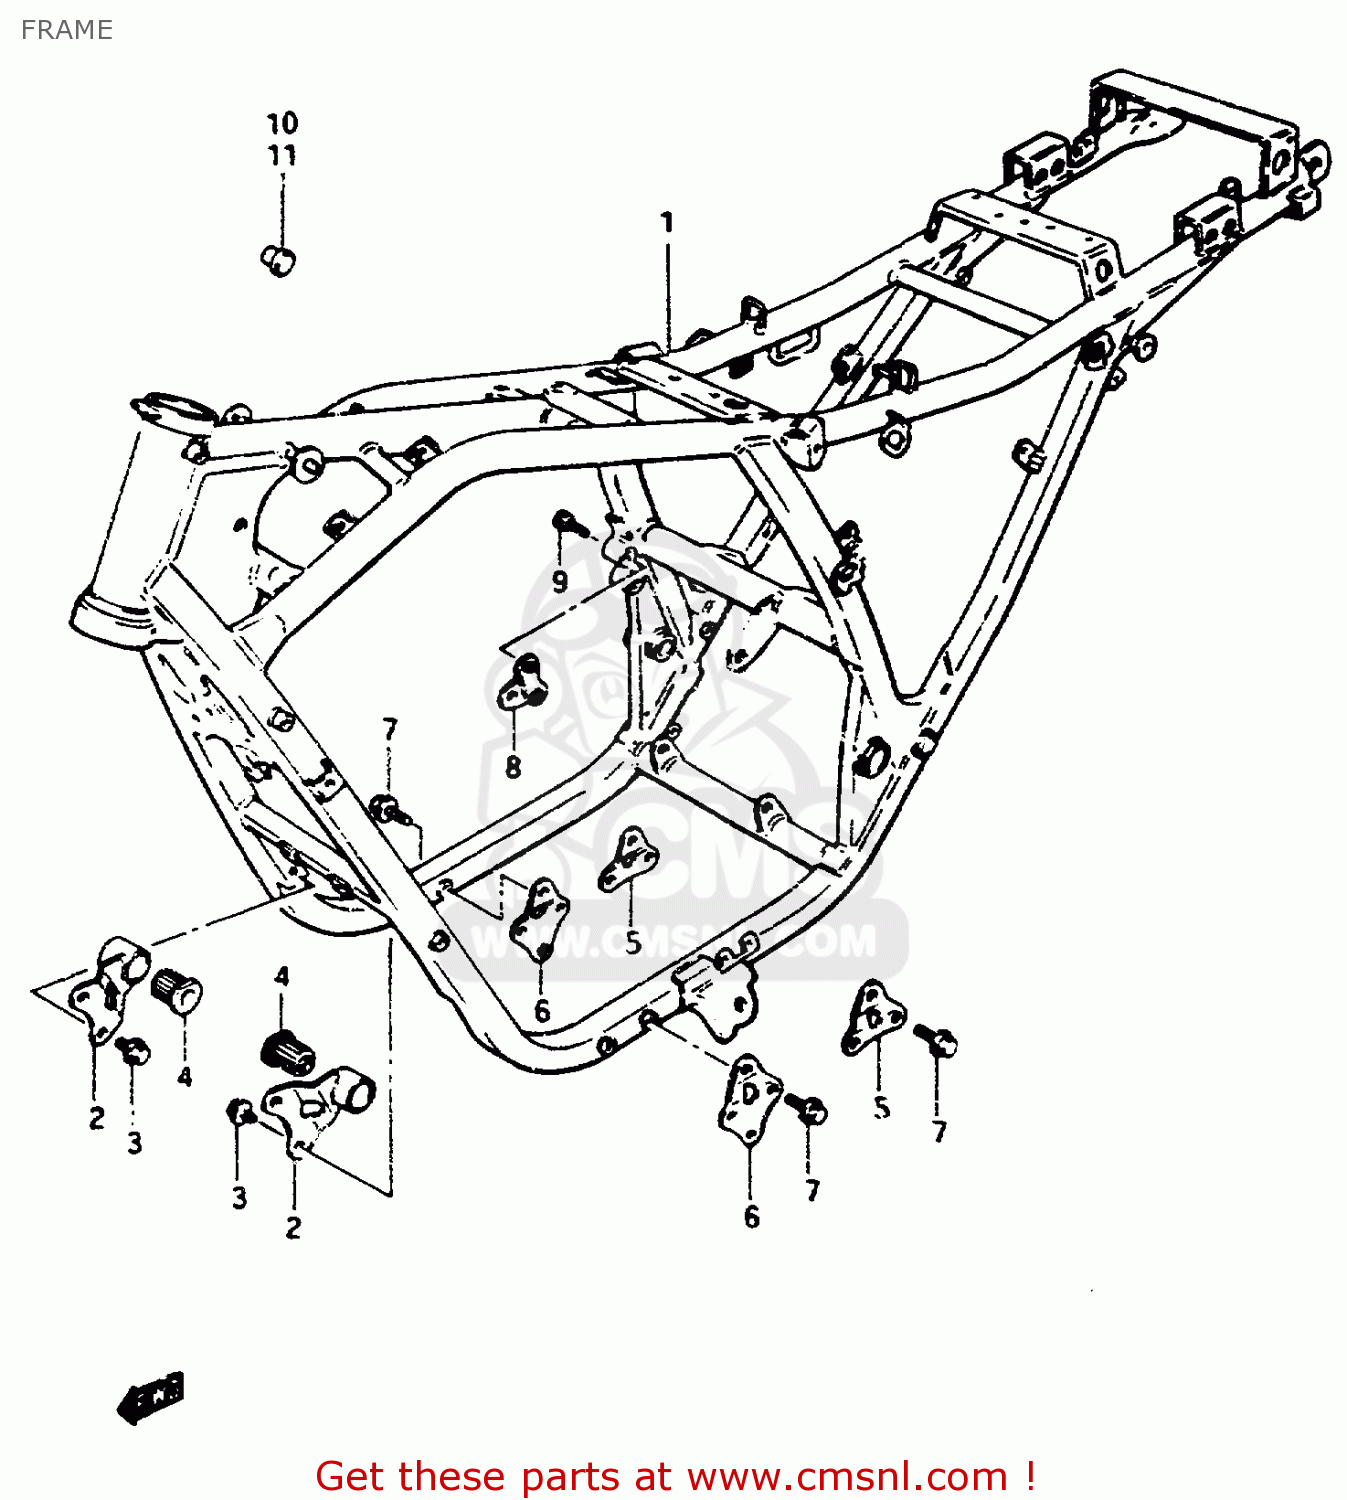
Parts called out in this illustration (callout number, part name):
1	FRAME (SILVER)
2	PLATE,ENGINE MOUNTING NO
3	BOLT 8X12
4	BUSH
5	PLATE,ENGINE MOUNTING
6	PLATE,ENGINE MOUNTING NO
7	BOLT 8X12
8	PLATE,ENGINE MOUNTING
9	BOLT
10	CAP(OD:10)
11	PLUG
